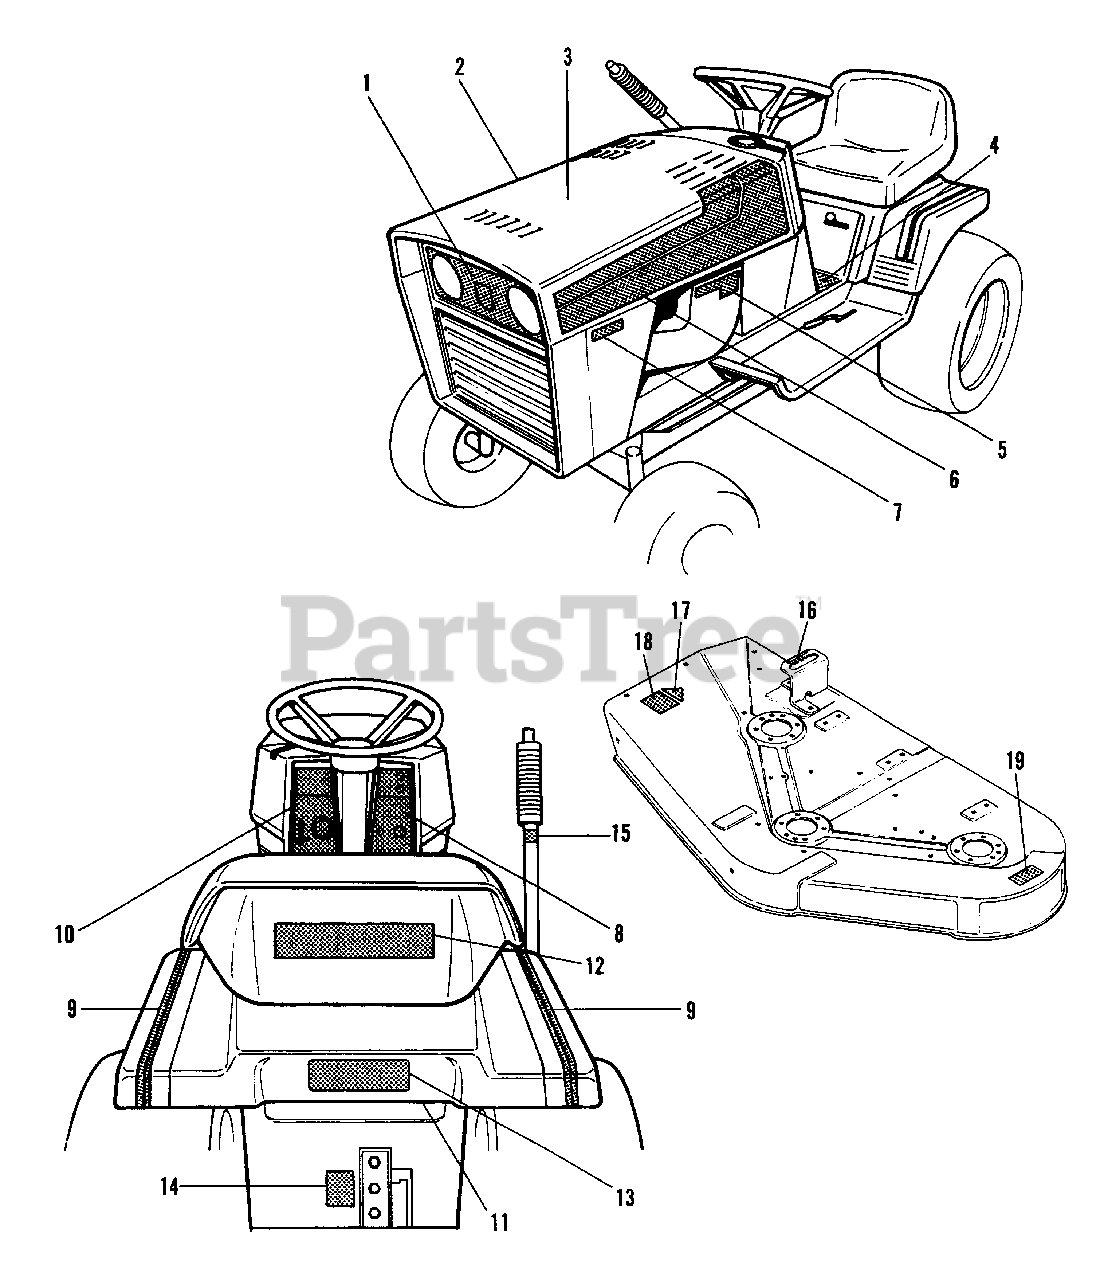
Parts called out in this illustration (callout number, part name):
1	DECAL, Grille
2	DECAL, Hood Stripe, R.H.
3	DECAL, Drive Belts (6211)
3	DECAL, Drive Belts (6216 & 6218)
4	DECAL, Shift Pattern
5	DECAL, Engine, 16 H.P.
5	DECAL, Engine, 18 H.P.
5	DECAL, Engine, 11 H.P.
6	DECAL, Hood Stripe, L.H.
7	DECAL, 6211
7	DECAL, 6216
7	DECAL, 6218
8	DECAL, Dash, R.H. (6211 only)
8	DECAL, Dash, R.H. (6216 & 6218 only)
9	DECAL, Seat Deck
10	DECAL, Dash, L.H. (6211 only)
10	DECAL, Dash, L.H. (6216 & 6218 only)
11	DECAL, Battery
12	DECAL, Seat
13	DECAL, Cast Iron Trans.
14	DECAL, Rear P.T.O.
15	DECAL, Lift Lever
16	DECAL, Mower Height
17	DECAL, OPEI
18	DECAL, Warning
19	DECAL, Danger
